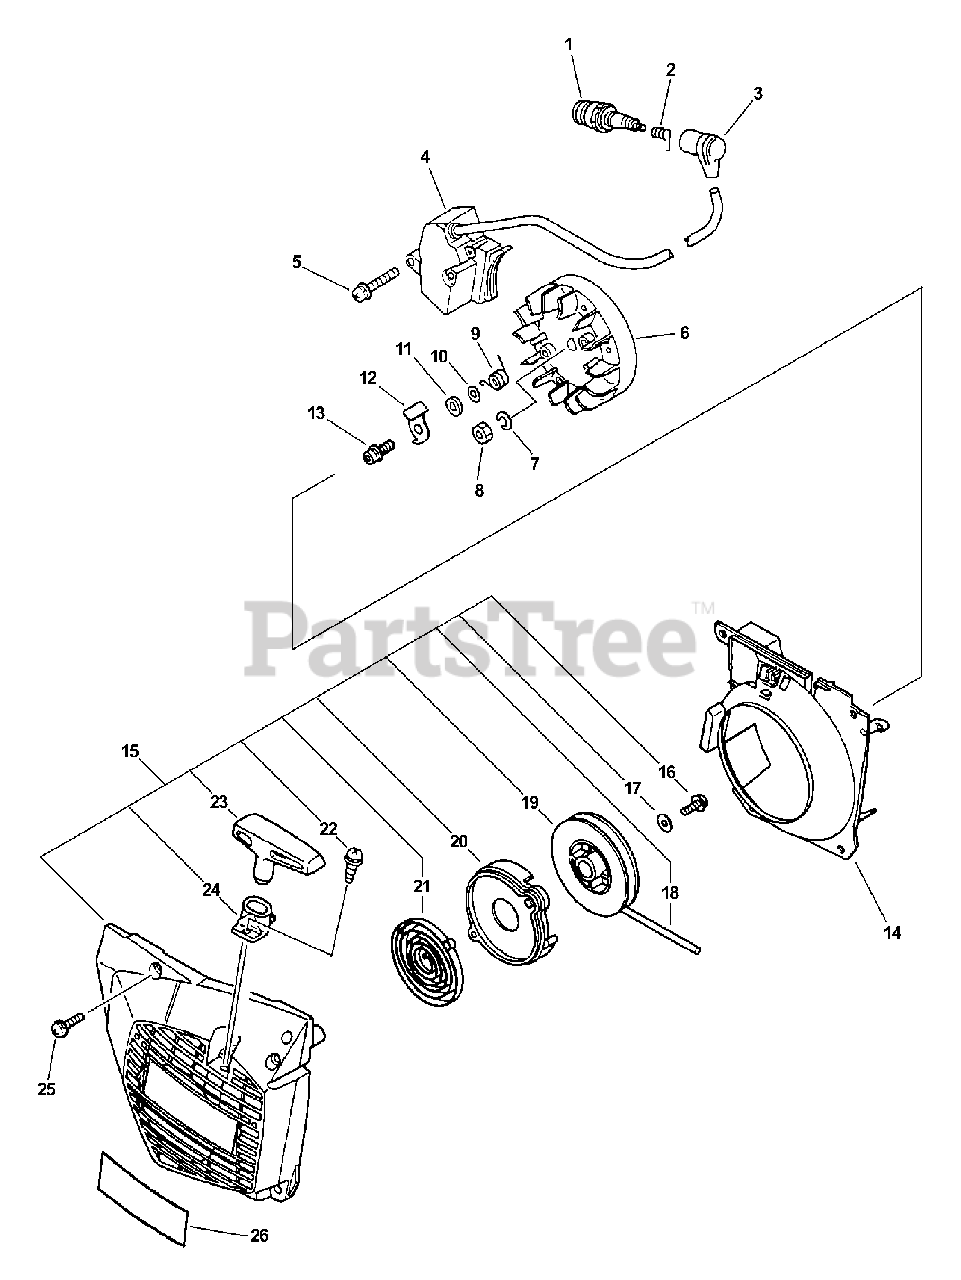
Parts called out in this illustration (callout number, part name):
1	SPARK PLUG -- BPM-7A
1	SPARK PLUG -- RCJ-6Y
2	TERMINAL, SPARK PLUG CAP
3	CAP, SPARK PLUG
4	COIL, IGNITION
5	SCREW - 4X30
6	FLYWHEEL
7	LOCKWASHER - 8
9	SPRING, RETURN
10	WASHER - 5
12	PAWL, STARTER
13	SCREW - 5X14
14	COVER, FAN
15	STARTER ASSY
16	SCREW - 5X12
17	WASHER - 5
18	ROPE, STARTER - 3.5X960
19	REEL, ROPE
20	PLATE, STARTER
21	SPRING, REWIND
22	SCREW - 3X14
23	GRIP, STARTER
24	GUIDE, ROPE
25	SCREW - 5X18
26	LABEL - ECHO
